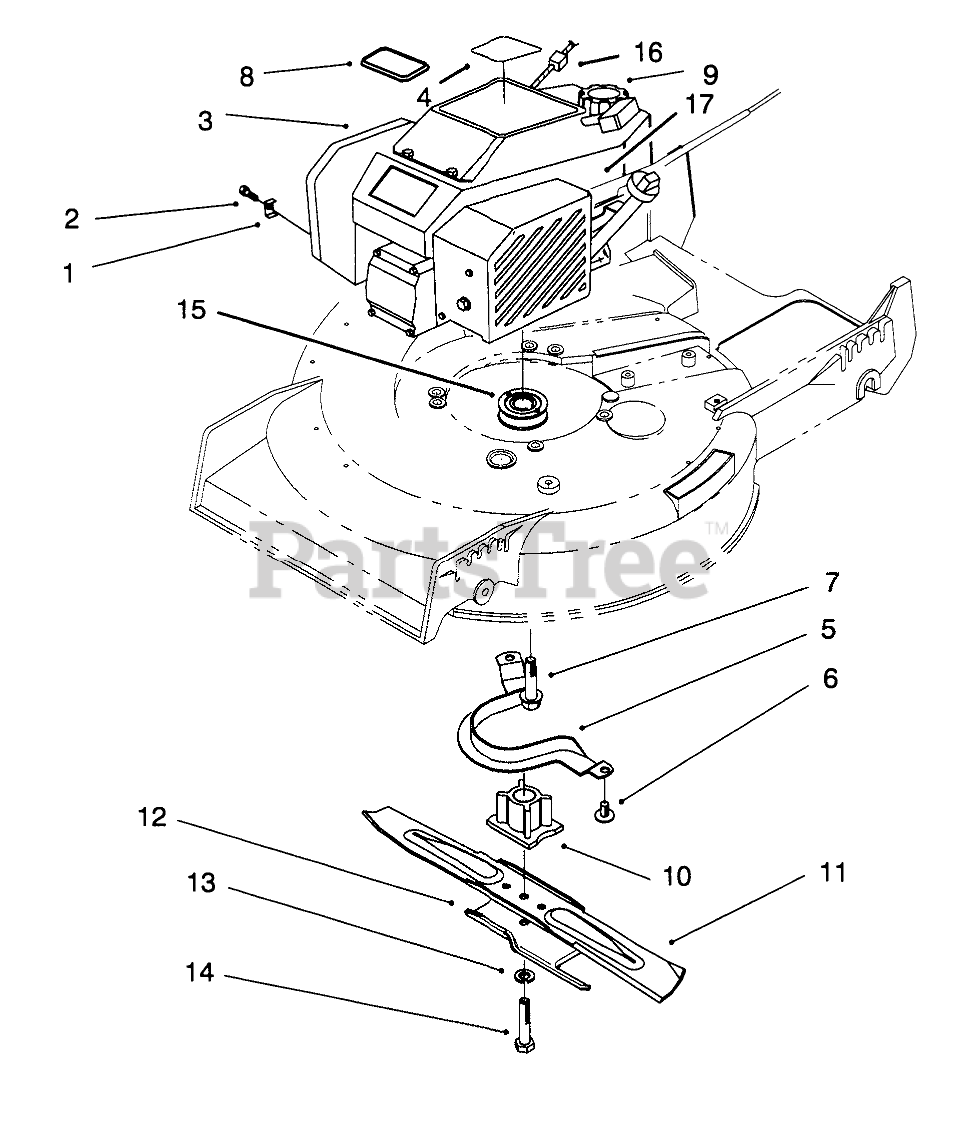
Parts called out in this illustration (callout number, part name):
1	CLAMP-CASING
2	CLAMP SCREW F/W ENGINE
3	Engine
4	DECAL - ENGINE
5	Guide-Belt
6	SCREW-HWHTF
7	SCREW-HWH
8	PLATE-LOGO
9	ASSY FUEL CAP
10	BLADE RETAINER
11	Blade
12	Accelerator
13	WASHER-LOCK
14	SCREW-BLADE
15	PULLEY-DRIVE, ZONE START
16	STOP-ROPE
17	COVER - BRAKE F/W
